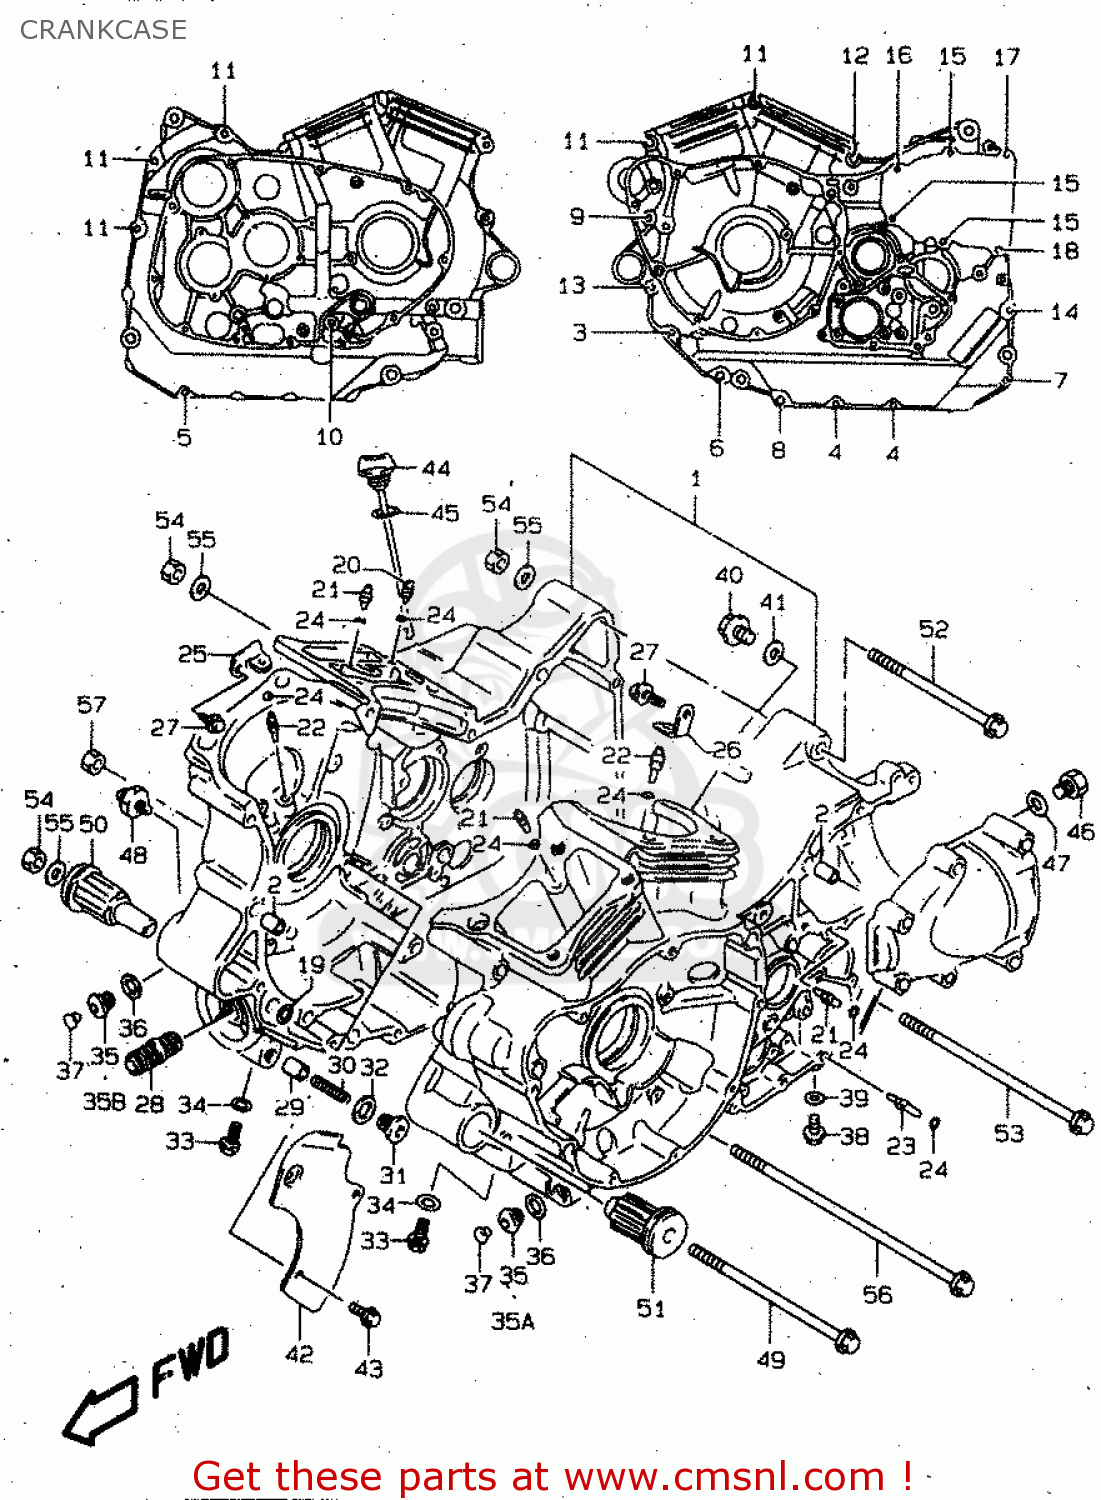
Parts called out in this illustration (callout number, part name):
1	CRANKCASE SET
2	PIN(8.4X11X20)
3	BOLT
4	BOLT
5	BOLT
6	BOLT
7	BOLT
8	BOLT(8X70)
9	BOLT
10	BOLT(8X115)
11	BOLT(8X95)
12	BOLT(8X50)
13	BOLT(8X70)
14	BOLT(8X80)
15	BOLT
16	BOLT
17	BOLT
18	BOLT
19	O RING(D:1.9,ID:12.6)
20	JET(2.2)
21	JET,AIR(14)
22	JET,PISTON COOLING(0.8)
23	JET,MISSION OIL(1.4)
24	O RING(D:1.2,ID:4)
25	PLATE,PISTON JET FR
26	PLATE,PISTON JET RR
27	BOLT
28	UNION,OIL STAND
29	PLUNGER,OIL CONTROLL
30	SPRING
31	PLUG
32	GASKET(16X22X2) (NAS)
33	BOLT
34	GASKET(8.2X14X1).6 (NAS)
35	PLUG,14X12
35A	PLUG,14X12
35B	PLUG(14X11.5)
36	GASKET(13.8X18.8X4.8) (NAS)
37	CAP(OD:12)
38	BOLT
39	GASKET(5.8X11X1.2) (NAS)
40	PLUG(12X10)
41	GASKET(12.1X16.2X3.7) (NAS)
42	PLATE,OIL SEPARATOR
43	BOLT
44	GAUGE,OIL LEVEL
45	O RING(D:3.1,ID:16.8)
46	BOLT
47	GASKET(12.1X16.2X3.7) (NAS)
48	SWITCH ASSEMBLY,OIL PRESSURE
49	BOLT(10X155)
50	BUSH,ENGINE MOUNTING,R
51	BUSH,ENGINE MOUNTING
52	BOLT(10X135)
53	BOLT(10X180)
54	NUT
55	WASHER
56	BOLT(10X225)
57	NUT
